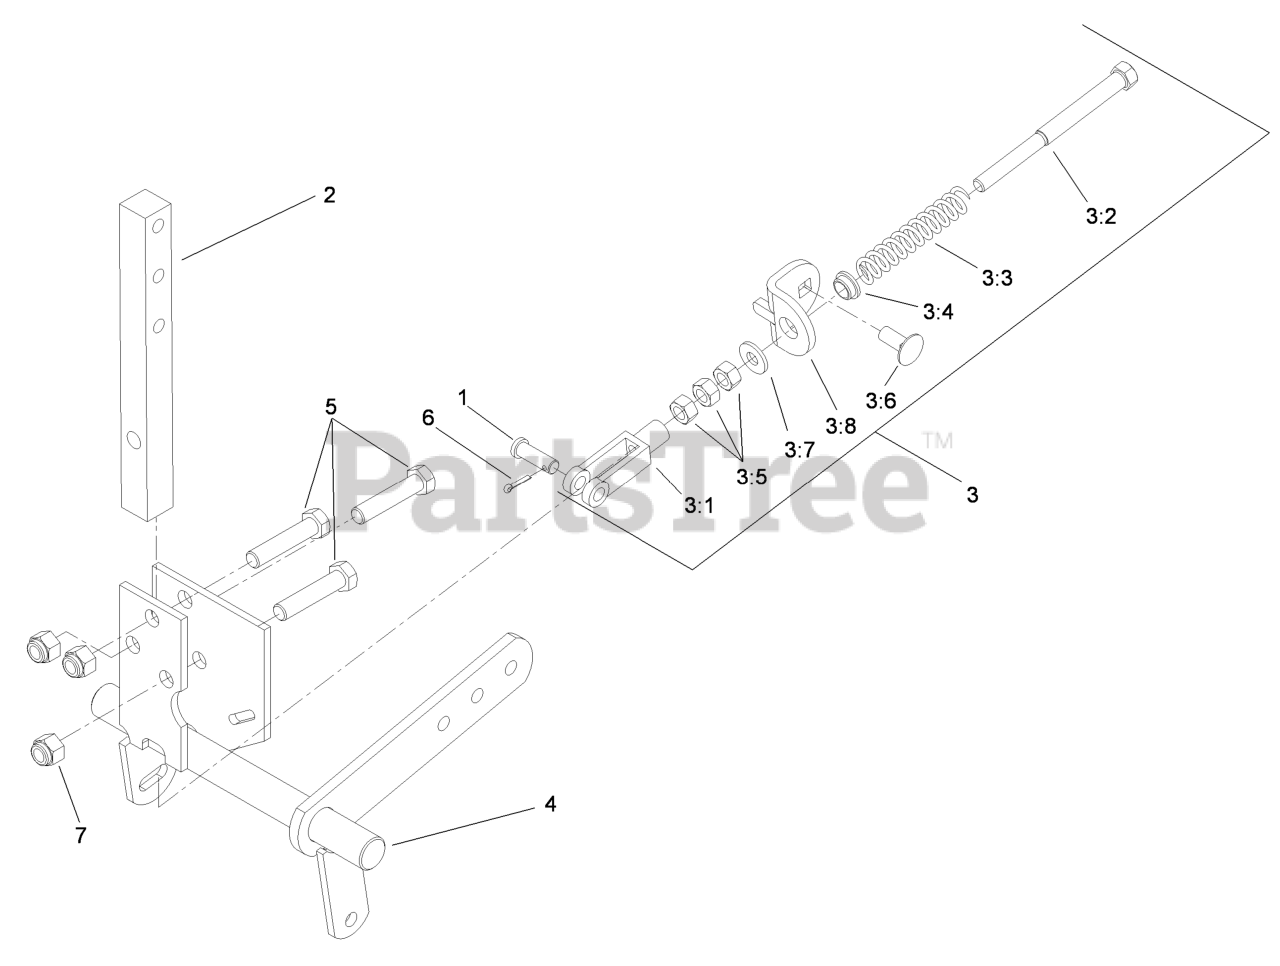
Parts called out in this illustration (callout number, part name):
1	PIN-CLEVIS
2	ARM-SHAFT, CONTROL
3	NEUTRAL RETURN ASM
3:1	YOKE-ADJUSTABLE
3:2	BOLT-RETURN, NEUTRAL
3:3	SPRING-RETURN, NEUTRAL
3:4	BUSHING-NYLON, FLANGED
3:5	NUT-HEX
3:6	SCREW-CARR
3:7	WASHER-FLAT
3:8	TAB-ADJUSTMENT
4	CONTROL-MOTION, RH
5	SCREW-HH
6	PIN-COTTER
7	NUT-LOCK, NI
